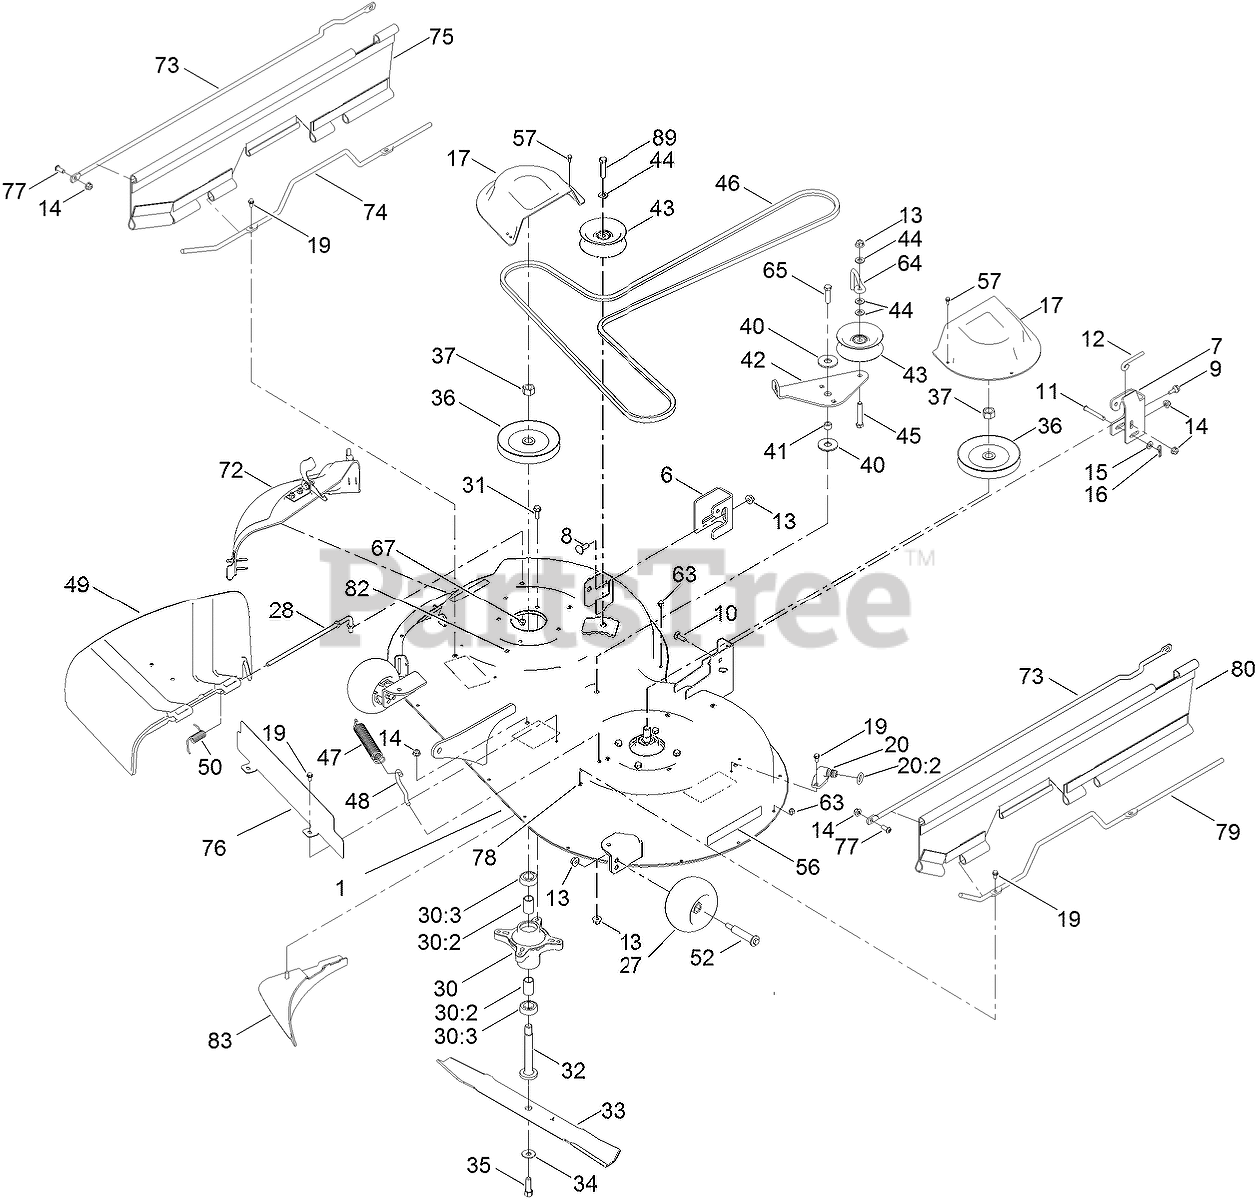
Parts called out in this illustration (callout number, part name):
1	42 INCH DECK AND DECAL ASM
6	BRACKET-HANGER, RH
7	BRACKET-HANGER, LH
8	BOLT-CARR
9	SCREW-SHOULDER,HWH
10	SCREW-CARR
11	PIN-CLEVIS
12	ROD-LEVEL, DECK
13	NUT-HF, NI
14	NUT-HF, NI
15	WASHER-PLAIN
16	PIN-COTTER
17	COVER-BELT
19	SCREW-HWH
20	FITTING-WASHOUT
20:2	O-RING
27	ROLLER-SCALP, ANTI
28	ROD-PIVOT
30	SPINDLE ASM
30:2	SPACER
30:3	BEARING-BALL
31	SCREW-TAPTITE
32	SHAFT-SPINDLE
33	BLADE-MULCH
34	WASHER-BELLEVILLE
35	SCREW-HH
36	PULLEY
37	NUT-HEX
40	WASHER-FRICTION, COMPOSITE
41	SPACER
42	ARM-IDLER
43	PULLEY-IDLER, FLAT
44	WASHER-FLAT
45	SCREW-HH
46	V-BELT
47	SPRING-EXTENSION
48	HOOK-RETURN, SPRING
49	DEFLECTOR
50	SPRING-TORSION
52	BOLT-SHOULDER
56	DECAL-RECYCLER
57	SCREW-TAPTITE
63	NUT-LOCK, NI
64	GUIDE-IDLER, BELT
65	SCREW-HH
72	42 INCH MULCH PLUG ASM
73	ROD-SUPPORT, UPPER
74	ROD-SUPPORT, LOWER (RH)
75	RIGHT GUARD ASM
76	SHIELD-FROUNT
77	SCREW-HSBH
78	NUT-RETAINING
79	ROD-SUPPORT, LOWER (LH)
80	LEFT GUARD ASM
82	NUT-RETAINING
83	BAFFLE-CLIPPING
89	SCREW-HH
